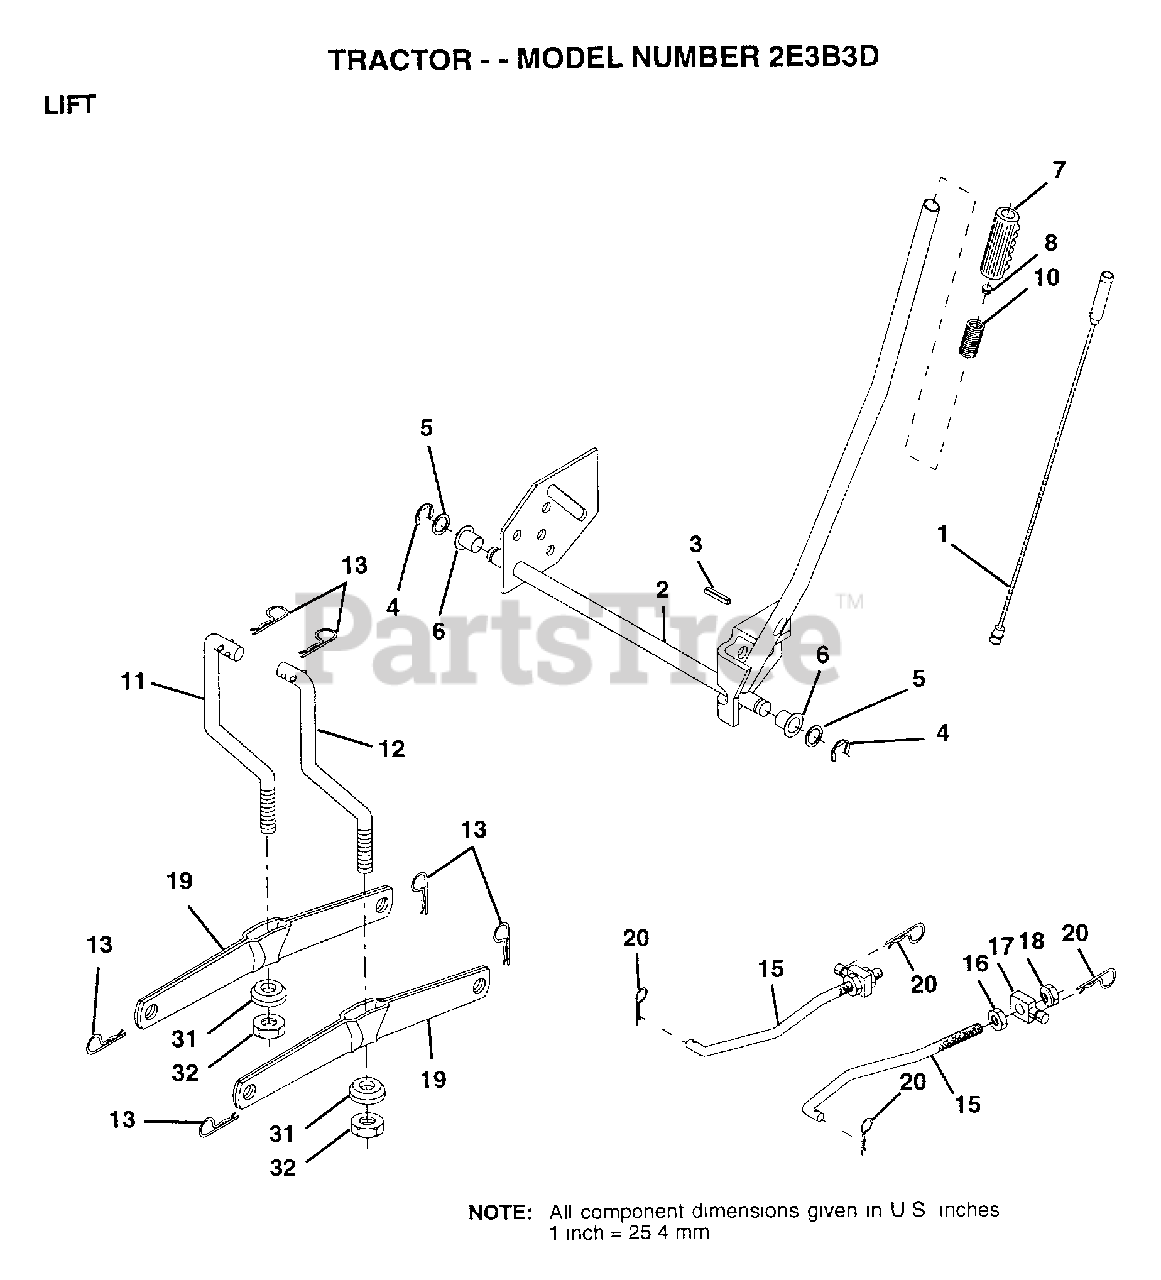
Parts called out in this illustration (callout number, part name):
1	WIRE ASM
3	PIN-GROOVE LT
5	WASHER
6	NYLON BEARING
7	GRIP
15	LINK.FRONT
16	NUT
17	TRUNION
18	NUT.LK.W/WSH.1/2.
19	ARM SUSP REAR
20	RETAINER.SPRING
31	BEARING PVT LH
32	NUT.CROWNLOCK.3/8
